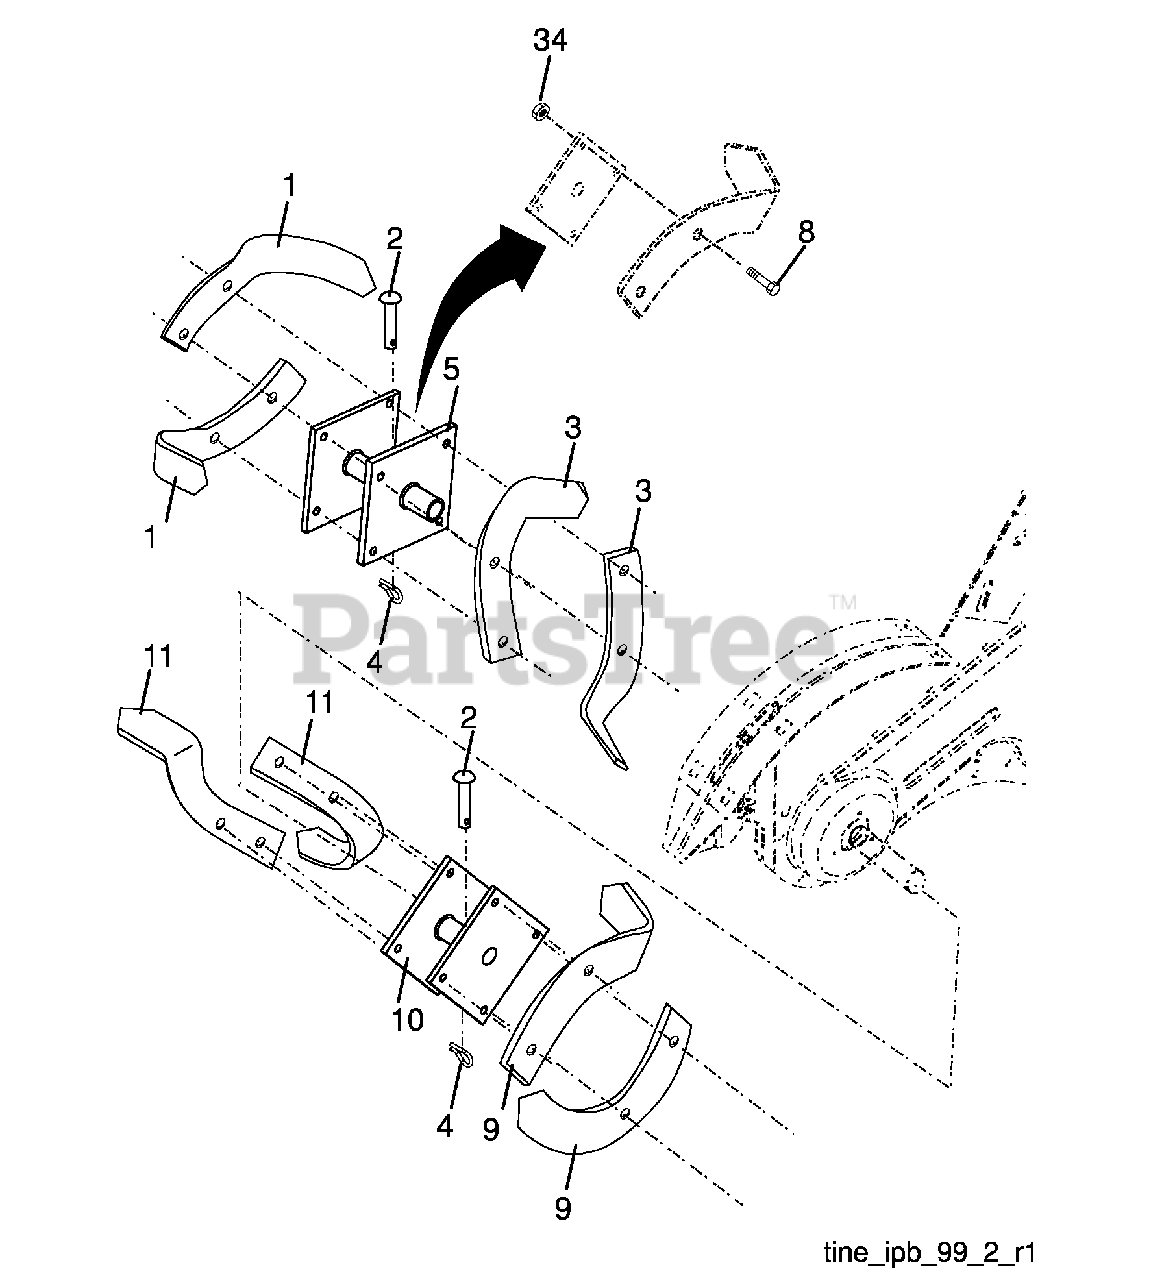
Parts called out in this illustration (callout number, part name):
1	Tine, Outer, L.H.
2	Clevis Pin
3	Tine, Inner, L.H.
4	Retainer, Spring Zinc
5	Assembly, Hub and Plate, L.H.
8	Bolt, Hex 3/8-24 x 1
9	Tine, Outer, R.H.
10	Assembly, Hub and Plate, R.H.
11	Tine, Inner, R.H.
34	Nut Crownlock 3/8-24
